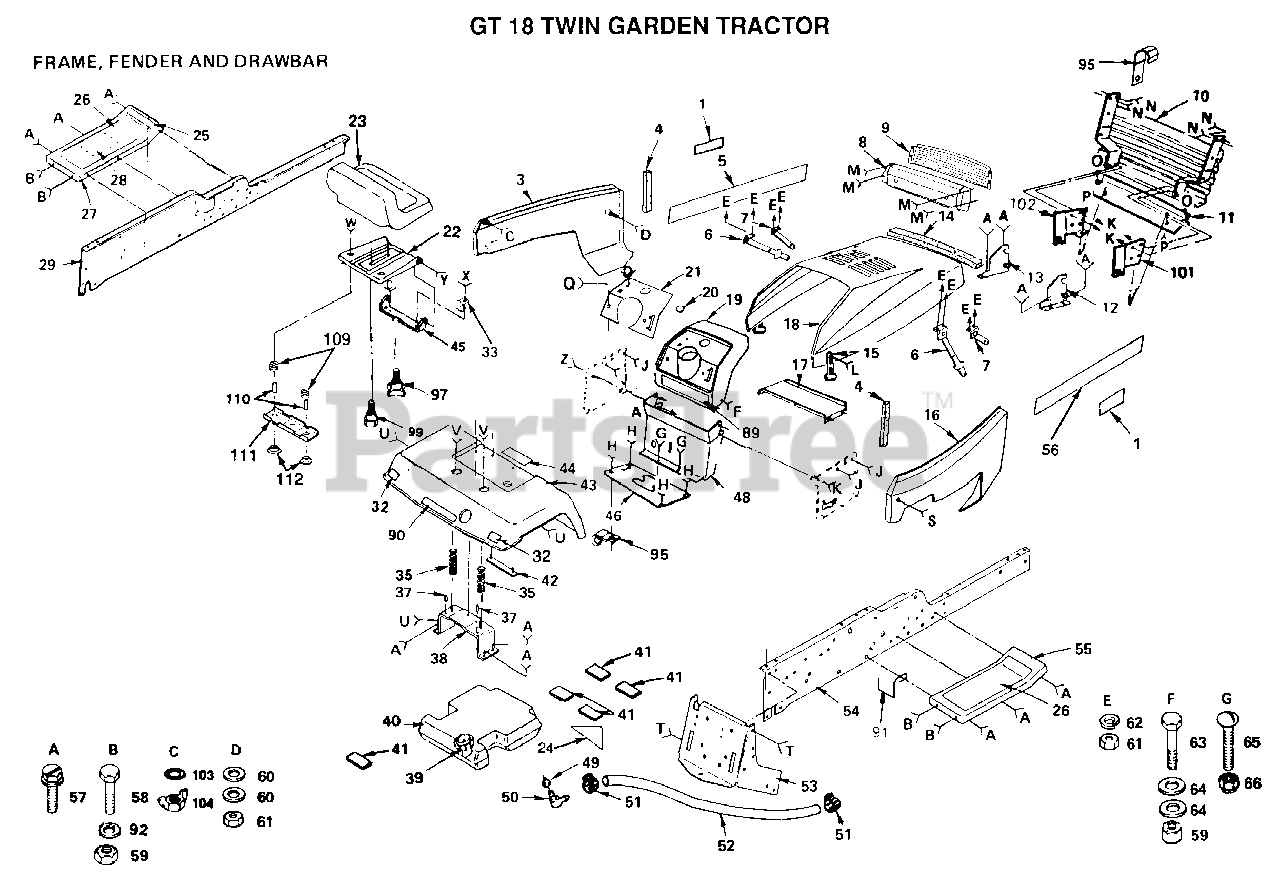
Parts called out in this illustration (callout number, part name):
4	FOAM STRIP T
5	ECAL - HOOD, L.H.
9	LENS LT
12	SUPPORT RH YTH
13	SUPPORT LH YTH
15	HOOD LATCH T
20	PLUG-DASH T
25	DECAL T
26	PAD FOOTREST T
28	DECAL T
32	REFLECTOR-TAIL YT
33	CLIP T
37	NUT-PUSH YT
41	PAD-SPACER LT
44	DECAL
46	CVR SHAFT GATE
48	DASH ASSEMBLY
49	BUSHING OUTLET T
50	FUEL TANK STEM GT
56	DECAL - HOOD R.H.
57	SCREW
60	WASHER PM
63	BOLT
64	WASHER
65	SCREW
91	BELT RETAINER GT
92	WASHER
97	"KNOB 1/2"" YT"
101	SUPPORT RH YTH
102	SUPPORT LH YTH
103	LOCKWASHER GT
109	SPRING
110	SPACER SPLIT
111	BRKT SWITCH
112	BUSHING
